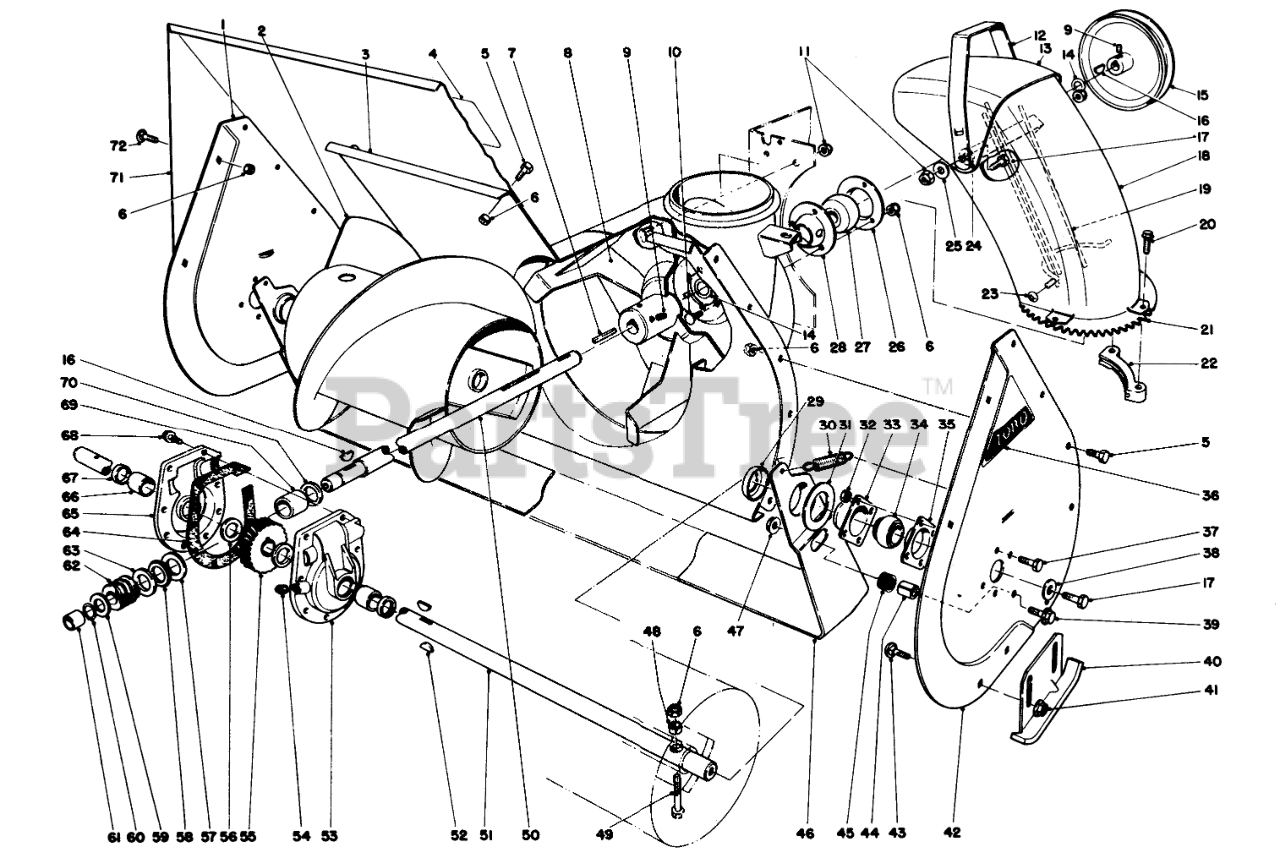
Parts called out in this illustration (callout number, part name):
1	Sideplate Auger Right
2	Auger Right
3	Auger Housing
4	Decal
5	SCREW-HH
6	NUT-LOCK, NI
8	IMPELLER WA RO
9	SCREW-SET, SQH
10	BOLT-CARR
11	NUT-LOCK, CONE
12	DEFLECTOR HANDLE B
13	Chute Deflector
14	WASHER
15	IMPELLER PULLEY
16	KEY-WOODRUFF
17	SCREW-HH
18	Chute
19	CHUTE GUARD WA 24
20	SPECIAL SCREW
21	Chute Swivel Gear
22	CHUTE RETAINER
23	NUT-PUSH
24	WASHER-RUBBER
25	WASHER-BELLEVILLE
26	FLANGE-CUP, BEARING
27	Ball Bearing
28	FLANGE-CUP, BEARING
29	Positioner-Scraper
30	SPRING-TENSION
31	SCRAPER BLADE SPACER
32	NUT-LOCK, CONE
33	BEARING-FLANGE, FRONT
34	BEARING
35	BEARING-FLANGE, REAR
36	AUGER SIDE PLT DECAL
37	SCREW-HH
38	WASHER
39	SCREW-HHF
40	AUGER SKID WA R
41	NUT-HHF, WHIZ
42	Sideplate Auger Left
43	SCREW-CARR
44	SCRAPER STOP SPACER
45	SCRAPER STOP CUSHION
46	24 SCRAPER BLD
47	NUT-HF
48	SPACER-HUB, AUGER
49	Auger Bolt
50	Shaft Impeller
51	24 AUGER SHAFT
52	KEY-WOODRUFF
53	Gear Case (Incl. Ref. #67 & 68)
54	PLUG-PIPE, SQH
55	GEAR-WORM, 27T
56	WASHER-THRUST
57	WASHER-THRUST
58	BEARING-THRUST
59	WASHER-THRUST
60	Ring-Snap
61	BUSHING
63	THRUST-WASHER
64	asket
65	Gear Case (Incl. Ref. #67 & 68)
66	BUSHING
67	SEAL-OIL
68	SCREW-TAPTITE
69	BUSHING-SPECIAL
70	RING-QUAD
71	AUGER EXT 24 SCND R
72	SCREW-CARR
